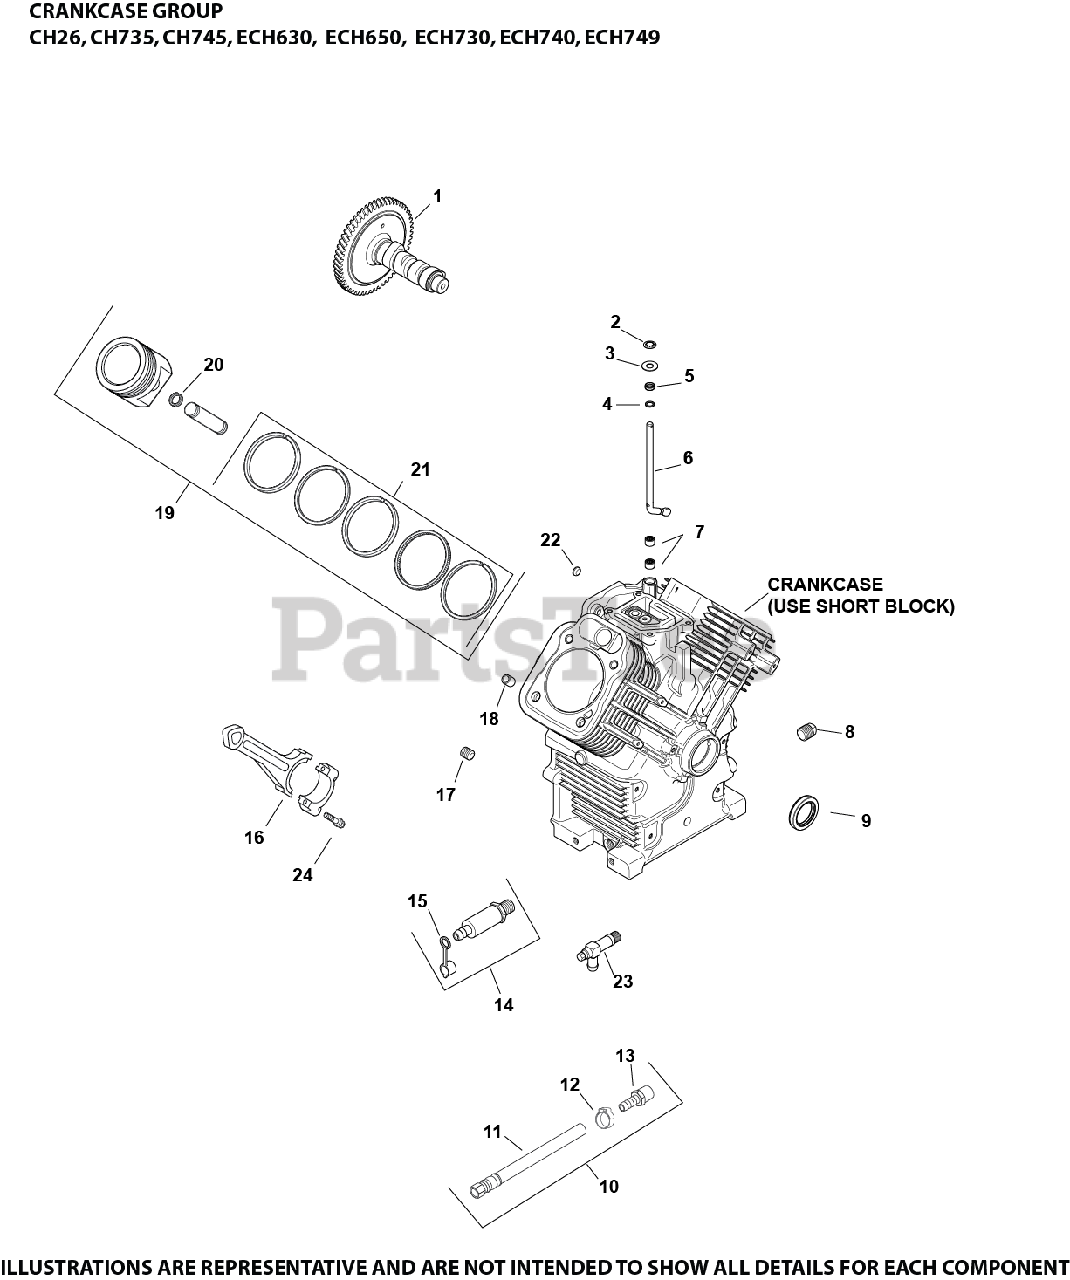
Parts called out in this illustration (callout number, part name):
1	KIT, CAMSHAFT
2	RETAINER, RING
3	WASHER, FLAT 9 MM
4	WASHER, FLAT 11/32"
5	SEAL, GOVERNOR CROSS SHAFT
6	SHAFT, GOVERNOR CROSS
8	PLUG, HD PIPE 3/8"
9	SEAL, OIL (HELIX LIP)
16	KIT, CONNECTING ROD ASSEMBLY USE 25 067 04-S
18	PIN, LOCATING
19	PISTON W/RINGS (STYLE B)(STD) - RING SET 25 108 01-S
19	PISTON W/RINGS (STYLE B)(.08) - RING SET 25 108 02-S
19	PISTON W/RINGS (STYLE B)(.25) - RING SET 25 108 03-S
19	PISTON W/RINGS (STYLE B)(.50) - RING SET 25 108 04-S
19	PISTON W/RINGS (STYLE A)(STD) - RING SET 24 108 14-S
19	PISTON W/RINGS (STYLE A)(.08) - RING SET 24 108 15-S
19	PISTON W/RINGS (STYLE A)(.25)-RING SET 24 108 16-S (#2587411S)
19	PISTON W/RINGS (STYLE A)(.50) - RING SET 24 108 17-S - USE 25 874 04-S
20	RETAINER, PISTON PIN
21	RING SET(STD)STYLE B-1.2mm Tp RING THICK
21	RING SET(.08)STYLE B-1.2mm Tp RING THICK
21	RING SET(.25)STYLE B-1.2mm Tp RING THICK
21	RING SET(.50)STYLE B-1.2mm Tp RING THICK
22	PLUG, CUP
24	KIT, ROD BOLTS
